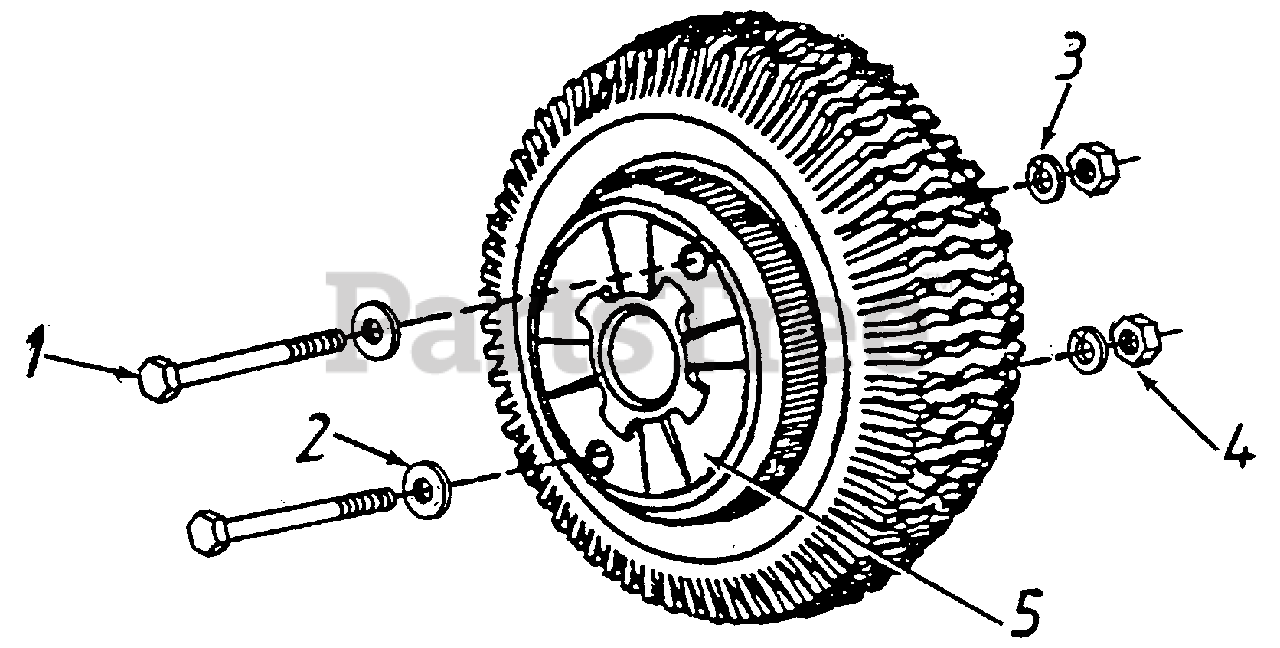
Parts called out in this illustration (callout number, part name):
1	Hex Bolt 3/8-16 x 7-1/2" Lg.
2	Fl-Wash. 3/8" I.D.
3	L-Wash. 3/8" I.D.
4	Hex Nut 3/8-16 Thread
5	31 Lb. Wheel Weights
